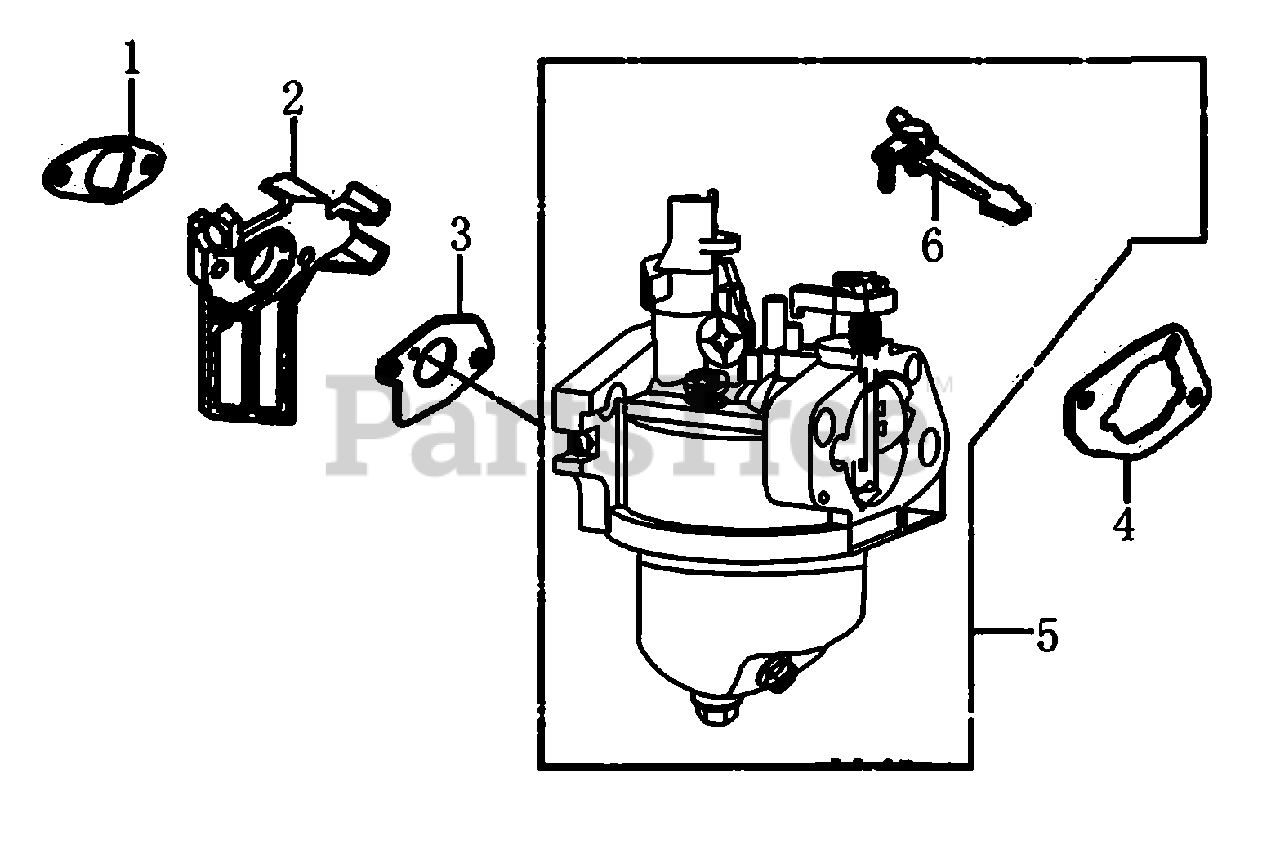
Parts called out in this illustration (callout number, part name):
1	GASKET, INSULATOR
2	INSULATOR, CARBURETOR
3	GASKET, CARBURETOR
4	GASKET, AIR CLEANER
5	CARBURETOR
6	LEVER ASSY, CHOKE
